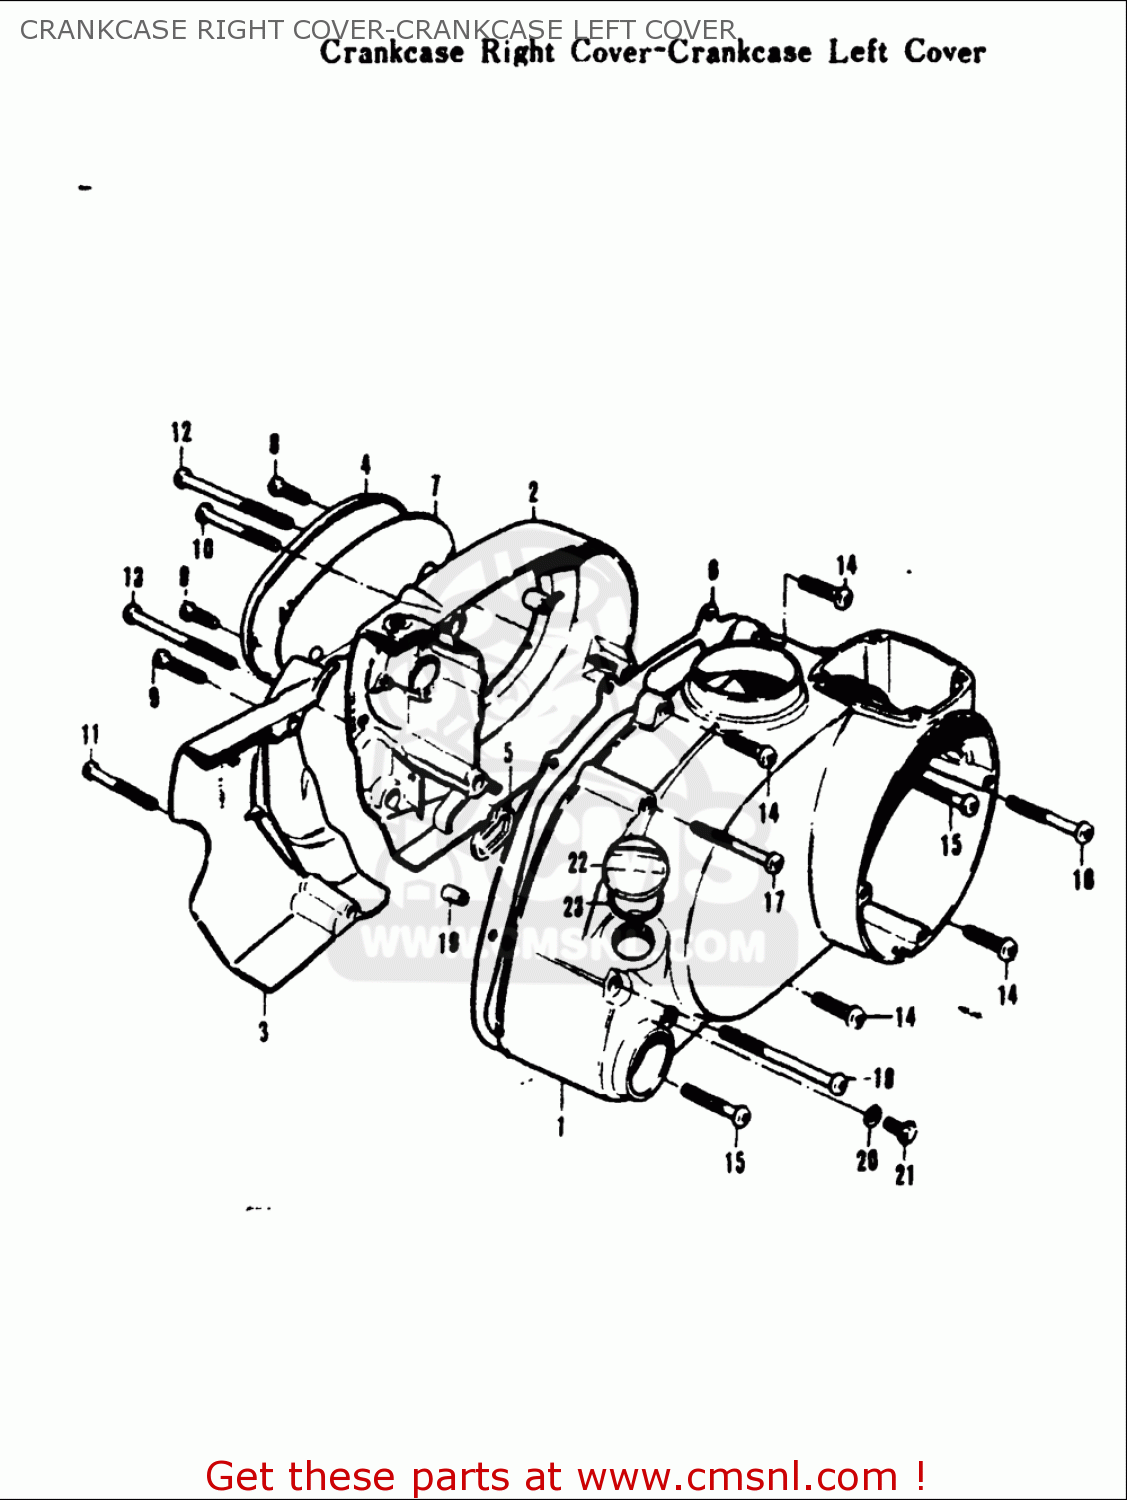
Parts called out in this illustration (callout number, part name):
6	GASKET,CLUTCH COVER (NAS)
14	SCREW
15	SCREW
16	SCREW
17	SCREW
18	SCREW
19	PIN
20	GASKET(6.2X11X1) (NAS)
22	PLUG SET
